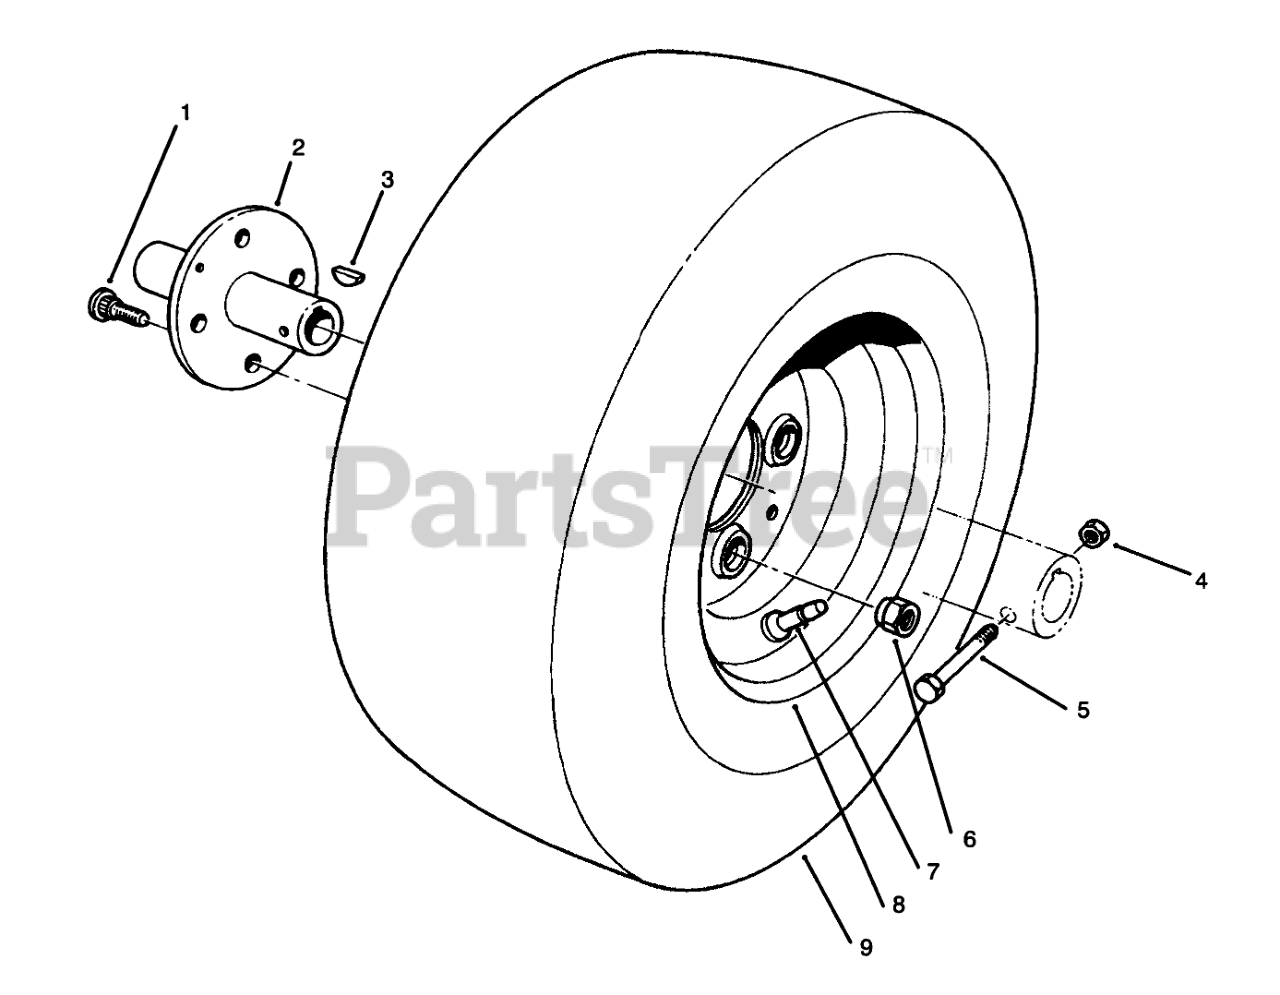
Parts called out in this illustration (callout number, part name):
1	1/2-20X1.25 BOLT
2	WHEEL HUB
3	KEY-WOODRUFF
4	NUT-LOCK, NI
5	SCREW-HH
6	NUT-LUG
7	STEM-VALVE
9	TIRE-4-Ply
